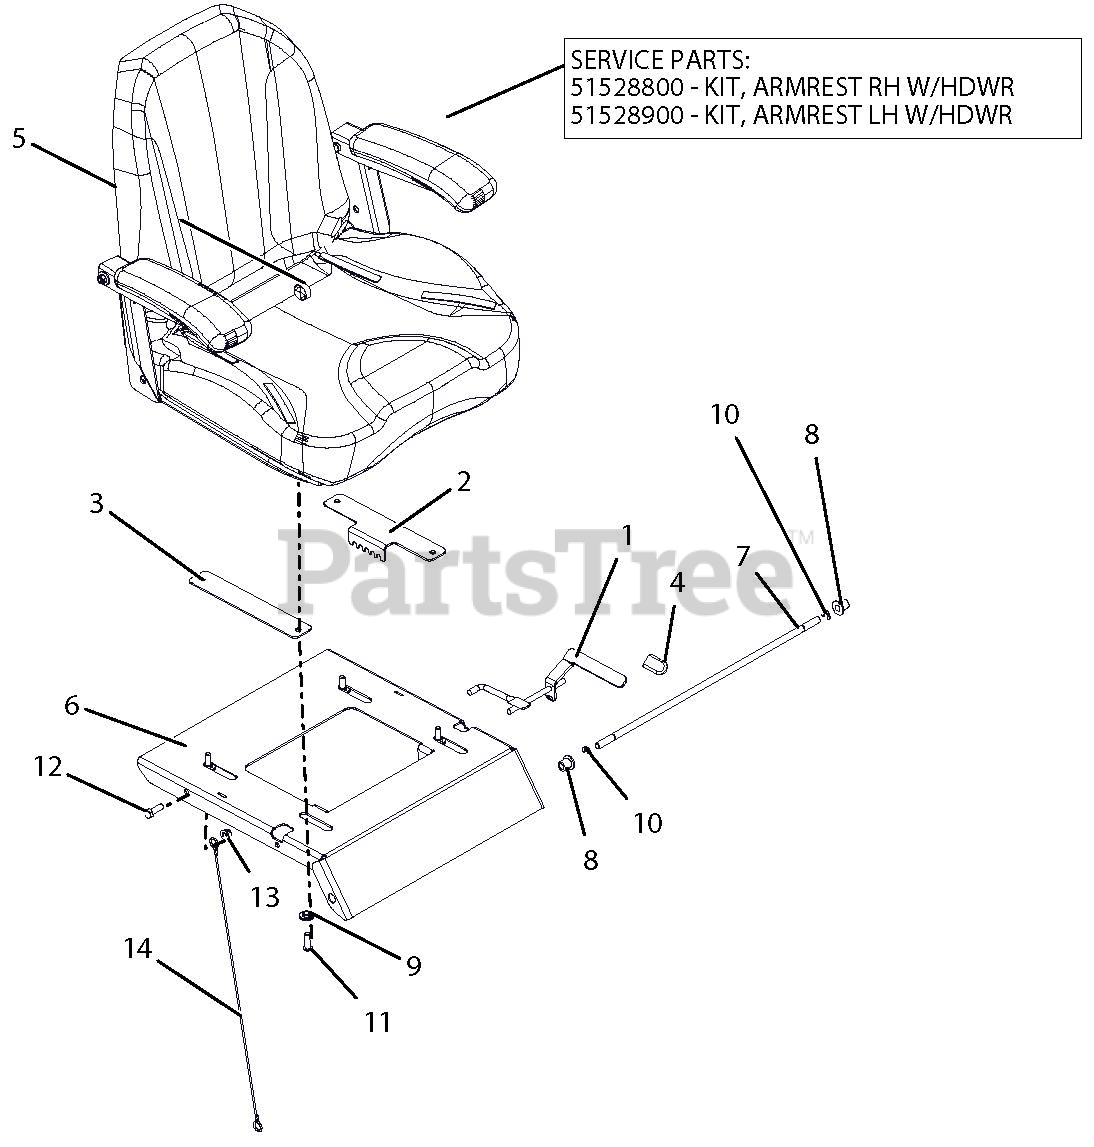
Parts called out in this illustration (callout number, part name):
1	WLDMT, ADJUSTABLE SEAT LATCH
2	PLATE, ADJUSTABLE SEAT TRACK
3	PLATE, ADJUSTABLE SEAT SLIDE
4	GRIP, SEAT LEVER, GREY
5	SEAT, MOWER
5	KIT, ARMREST RH W/HDWR
5	KIT, ARMREST LH W/HDWR
6	PLATE, SEAT
7	ROD, SEAT PIVOT
8	BSHG, FLANGE .380 X .580 X .667 X .875
9	BSHG, FLG .325X.499X.26X.88
10	RING, RETAINING-E .375X.035
11	SCR-SKH .31-18X1.00 BTNHD YWZC
12	BLT-HEX .31-18X1.00 GR5 YWZC
13	NUT-LK-NYL-FLG .31-18 YWZC
14	CABLE, WIRE (LANYARD)-.093X19.5
